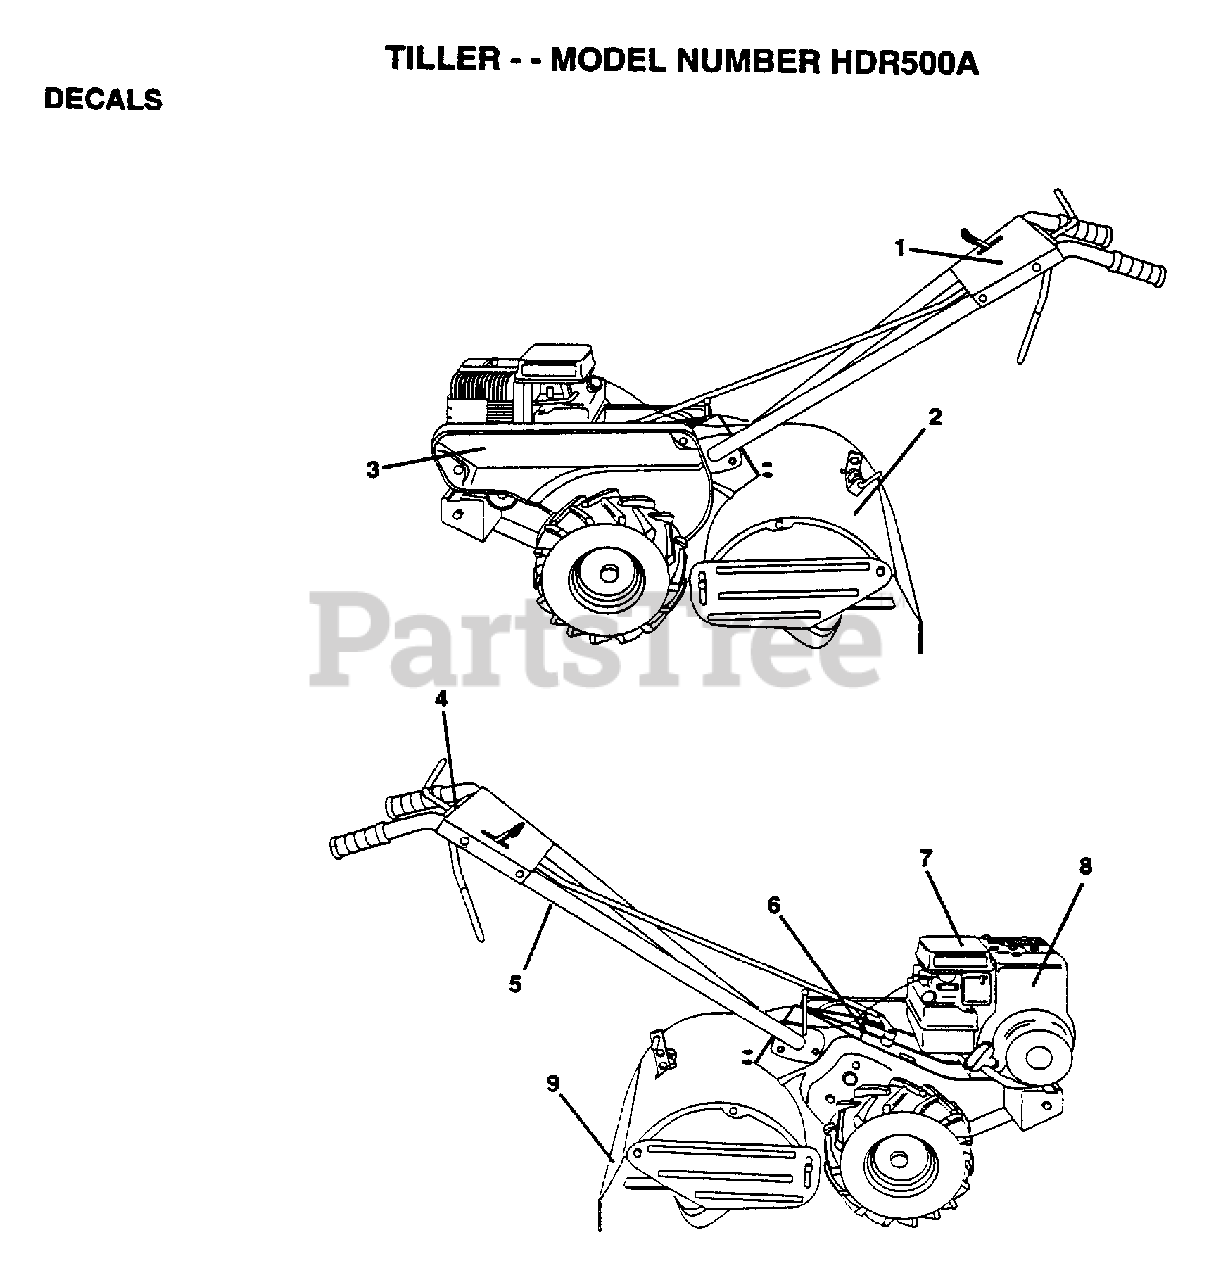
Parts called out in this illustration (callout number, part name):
1	DECAL.CNTRL.PNL.
2	DECAL.SHIELD.TINE
3	DECAL.GRD.BLT.5HP
4	DECAL.CONTROL
5	DECAL.HAND.PLACE
6	DECAL CRT
7	DECAL.CAUTION.E/S
8	DECAL, BRIGGS & STRATTON
9	DECAL.WARN.ROT.TI
